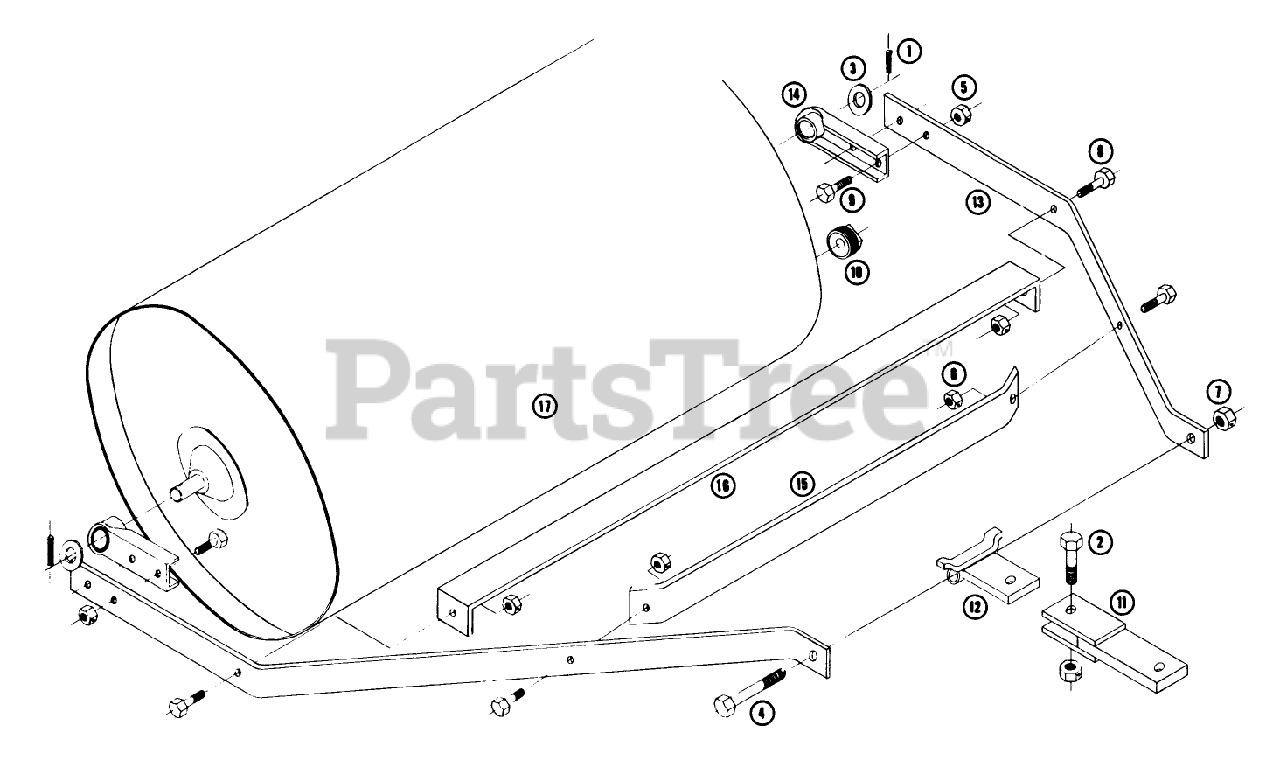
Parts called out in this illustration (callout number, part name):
1	Cotter Pin 3/16 X 1 1/2
2	H H C S
3	WASHER
4	HEX HD CAP SCREW
5	Nut
6	Nut
7	Nut
8	Bolt
9	Bolt
10	1" Pipe Plug
11	Hitch Bar W/A
12	Swivel Assembly
13	Frame Side Bar
14	Axle Pivot Tube
15	Frame Support
16	Scraper Bar
17	Tank W/A
18	DECAL-WHEEL HORSE
